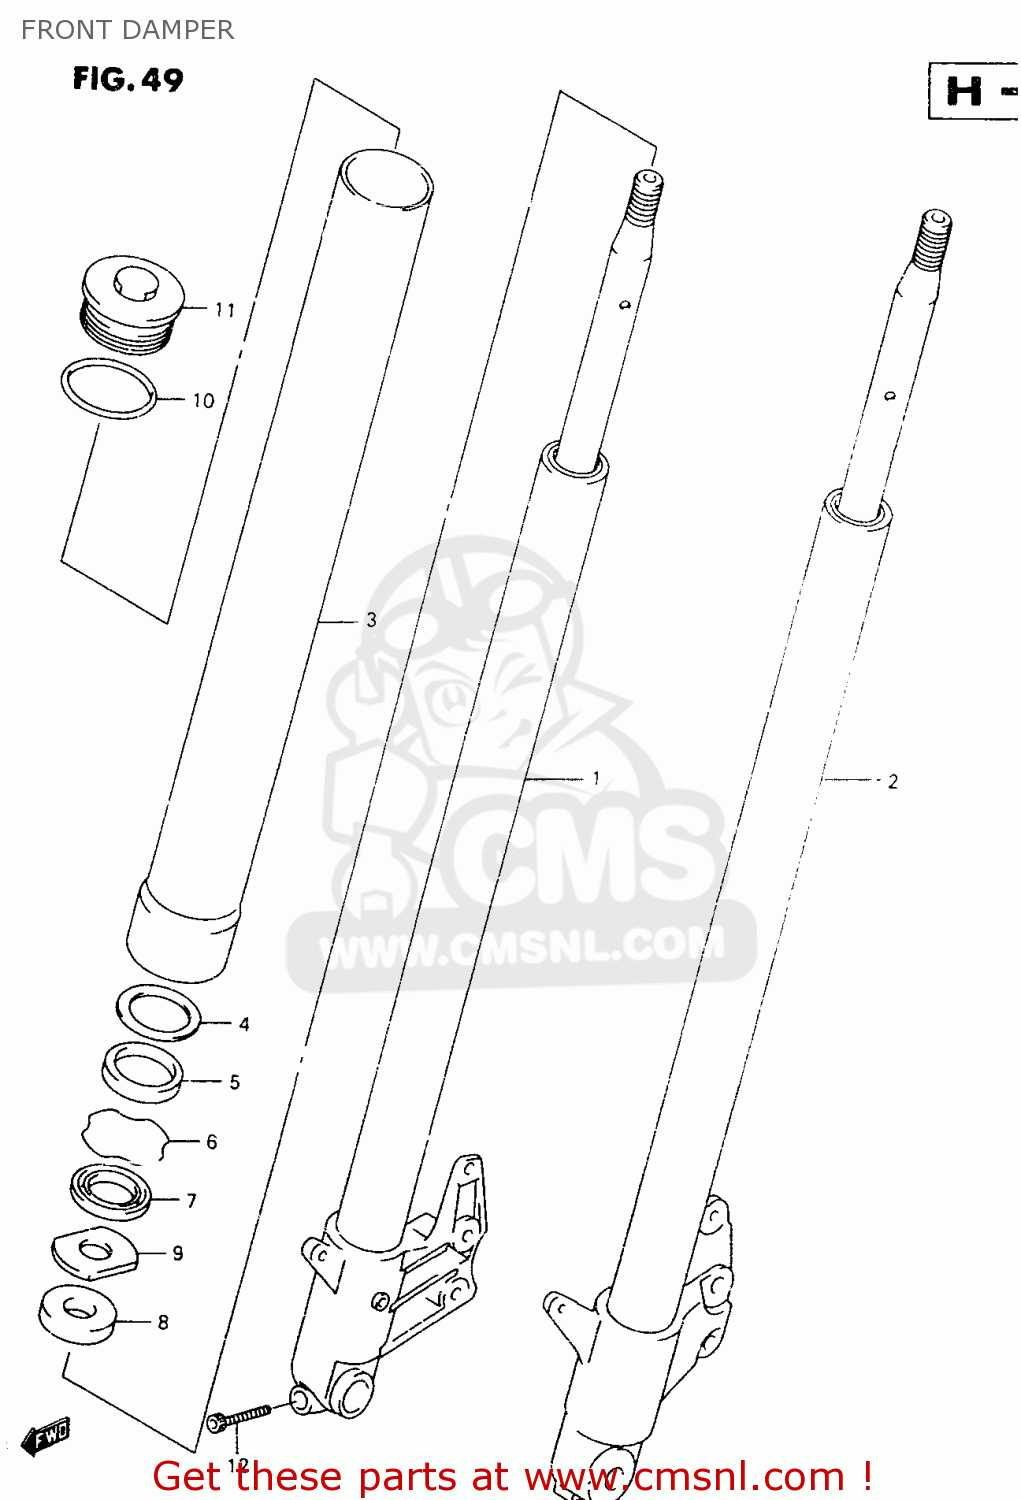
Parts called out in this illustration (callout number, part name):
1	DAMPER,FR FORK,R
2	DAMPER,FR FORK,L
3	TUBE,OUTER
4	WASHER,FORK OIL SEAL
5	SEAL,OIL
6	RING,OIL SEAL STOPPER
7	SEAL,DUST
8	RUBBER,CUSHION
9	NUT
10	O RING
11	CAP
12	BOLT,LWR
